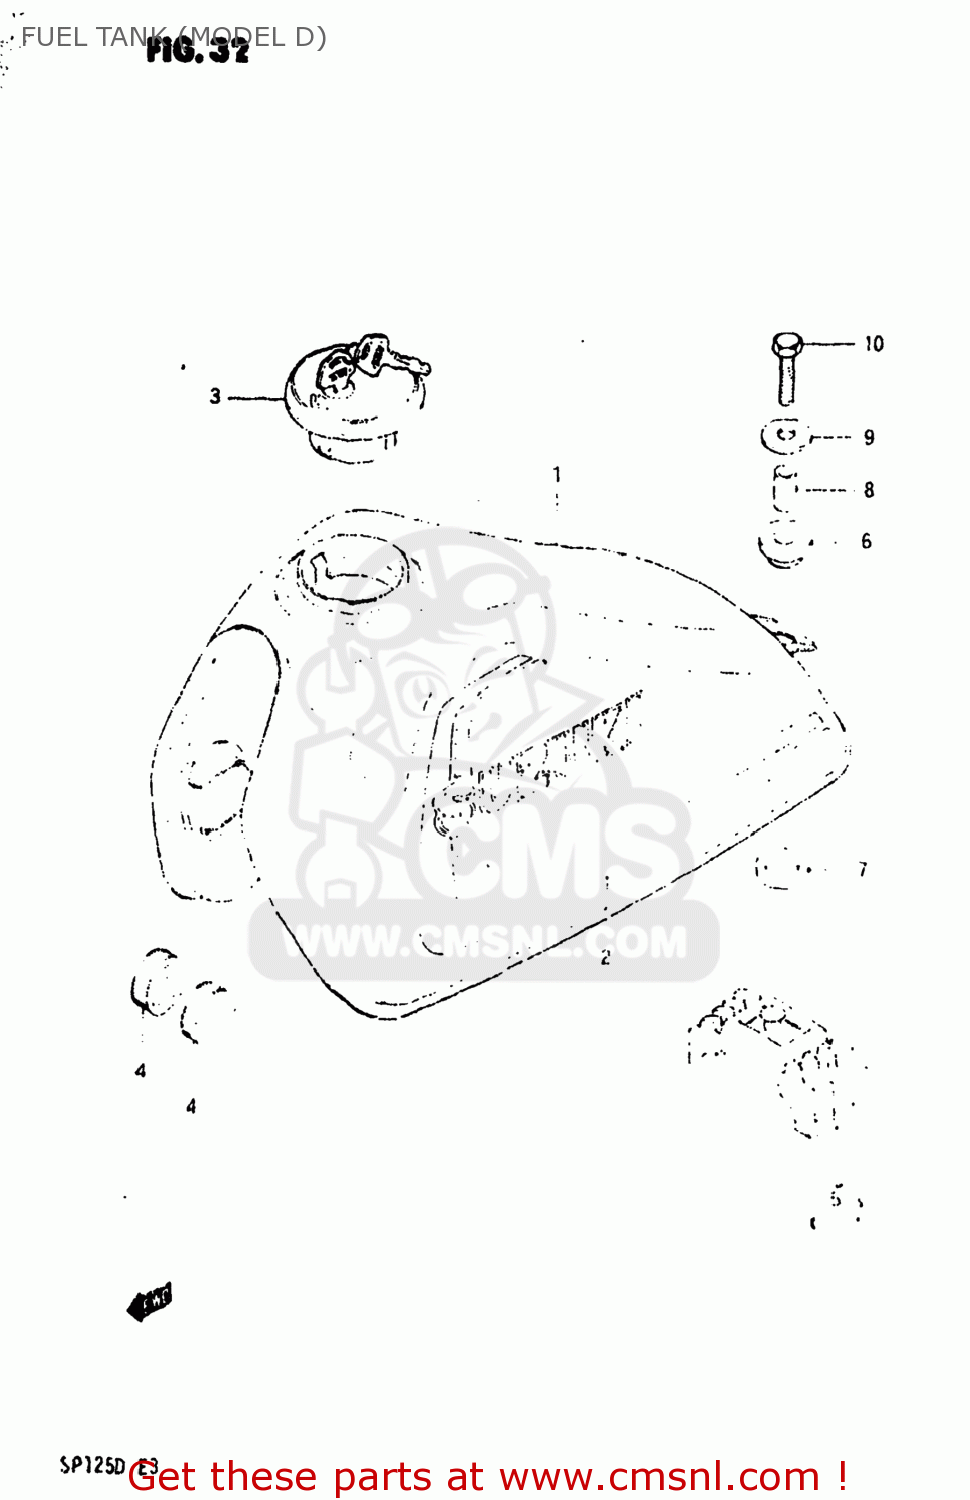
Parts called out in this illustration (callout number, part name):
1	TANK ASSEMBLY,FUEL
2	TAPE SET,FUEL TANK
3	CAP SET,FUEL TANK
4	CUSHION
5	CUSHION,FUEL TANK
6	CUSHION
7	CUSHION
8	SPACER(8.5X12X19)
9	WASHER (8.5X29X1.6)
10	BOLT (8X30)
